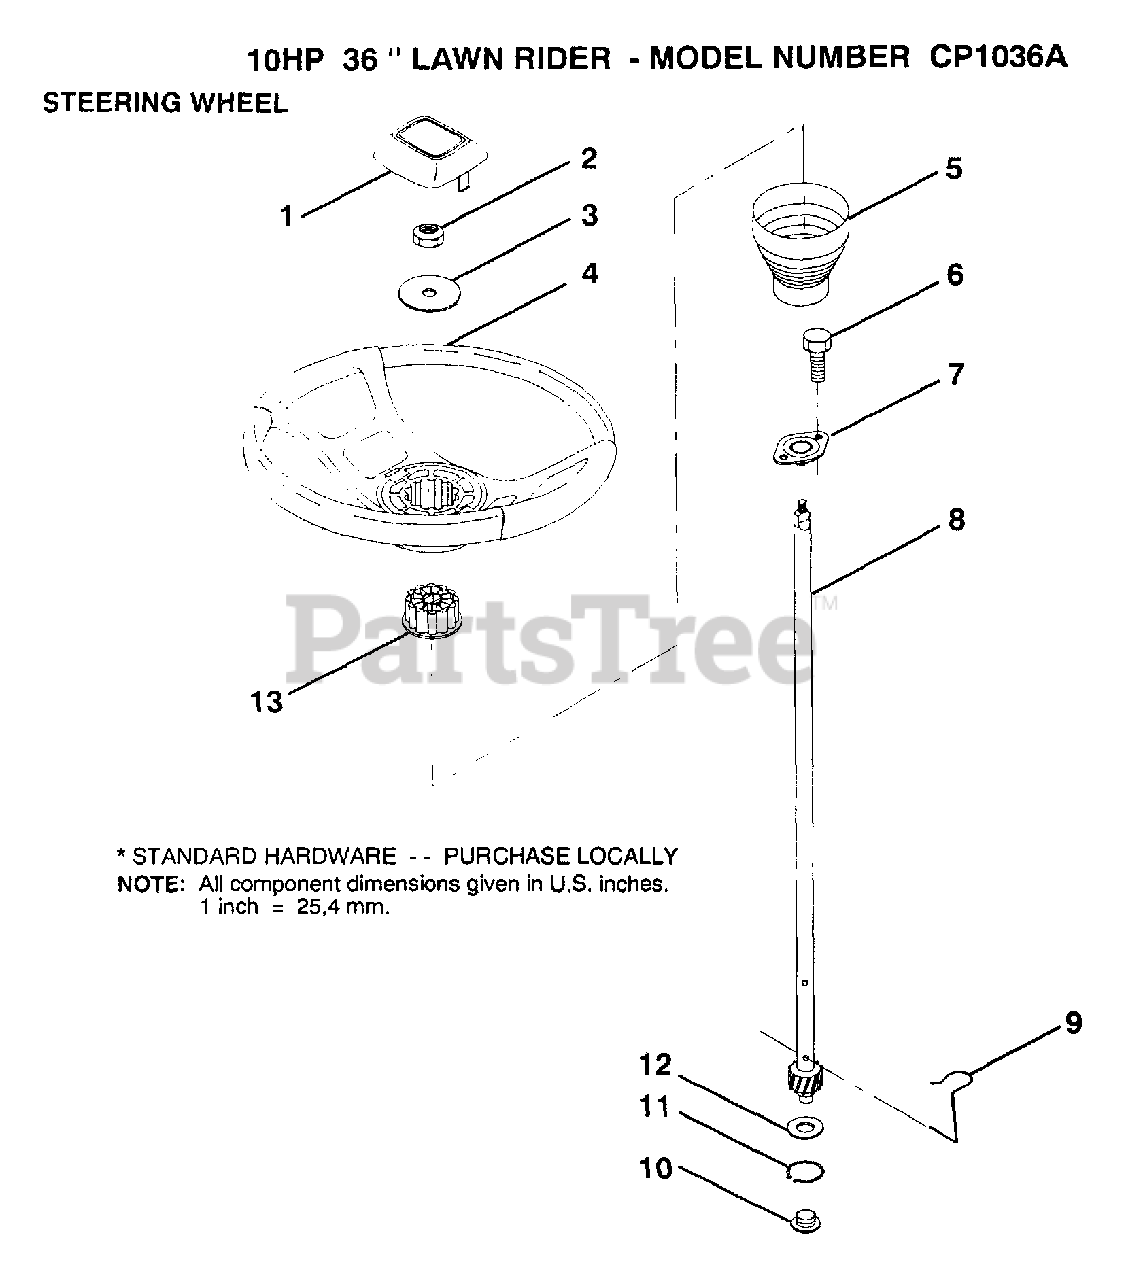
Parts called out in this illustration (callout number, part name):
1	ST WHL INSERT CAP
2	GRIPCO NUT
3	WASHER T
5	SLEEVE STEERING
9	STEERING CLIP
10	BUSHING STEER LWR
11	RING
12	WASHER LT
13	ADAPTER-WHEEL LT
